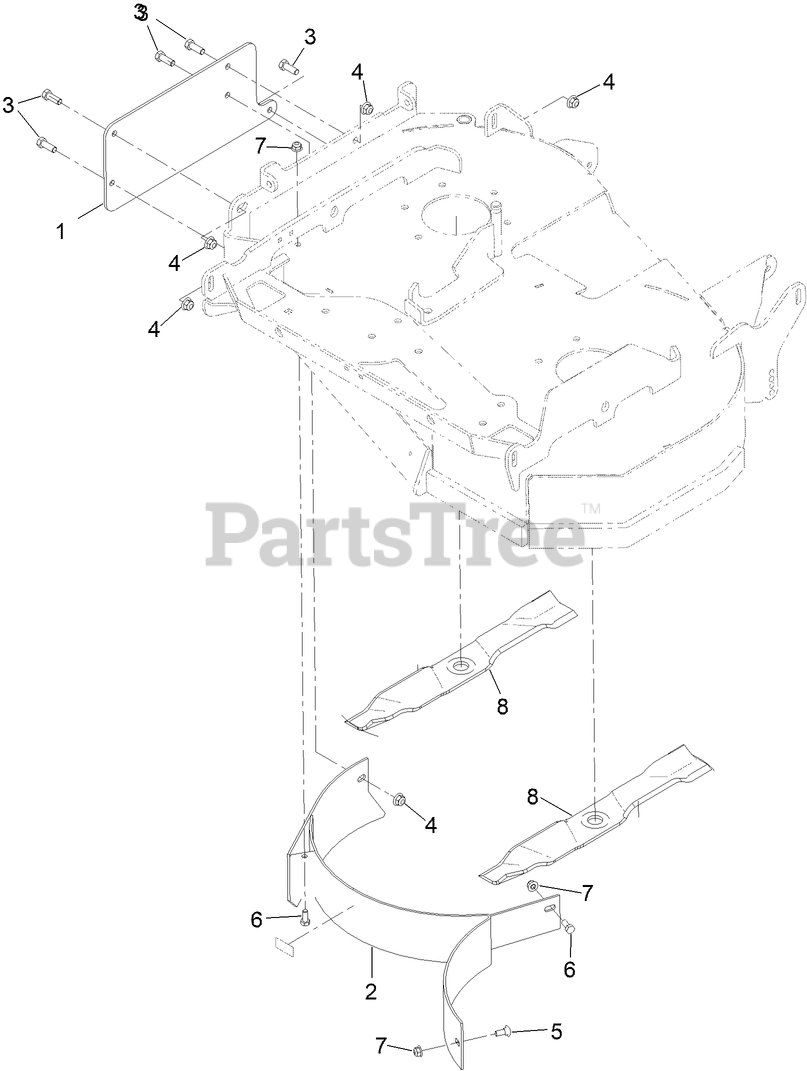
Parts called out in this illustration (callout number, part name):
1	PLATE, MULCH COVER
2	WLD,BAFFLE 36 MULCH
3	SCREW-HH
4	NUT-HF, NI
5	BOLT-CARR
6	SCREW-HH
7	NUT-HF, NI
8	BLADE, RECYCLER 18.0 (.94 HOLE)
